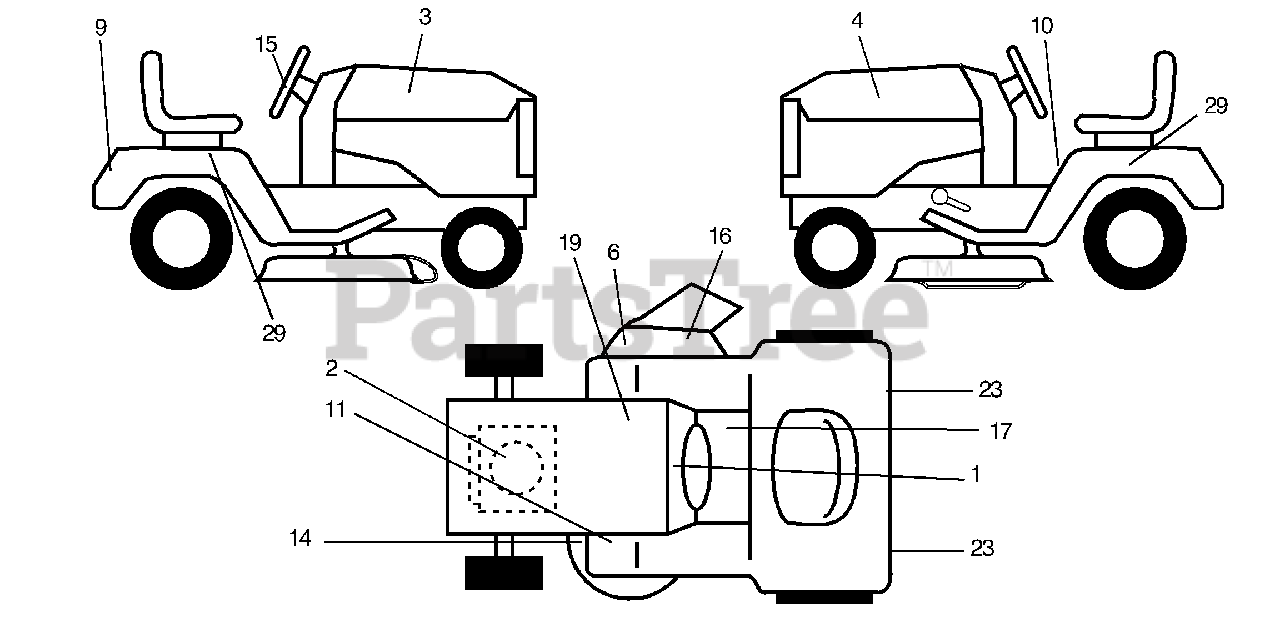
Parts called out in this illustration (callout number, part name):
1	Decal, Dash
2	Decal, Engine
3	Decal, Hood, RH
4	Decal, Hood, LH
6	Decal,Warning
9	Decal
10	Decal,Danger
11	Decal, Clutch/Brake
14	Decal, V-Belt Schematic
15	Decal, Ins. Whl. Strg.
17	Decal, Saddle Brake Parking
19	Decal, Battery
23	Reflector, Taillight
29	Decal, Fender Auto Trans
